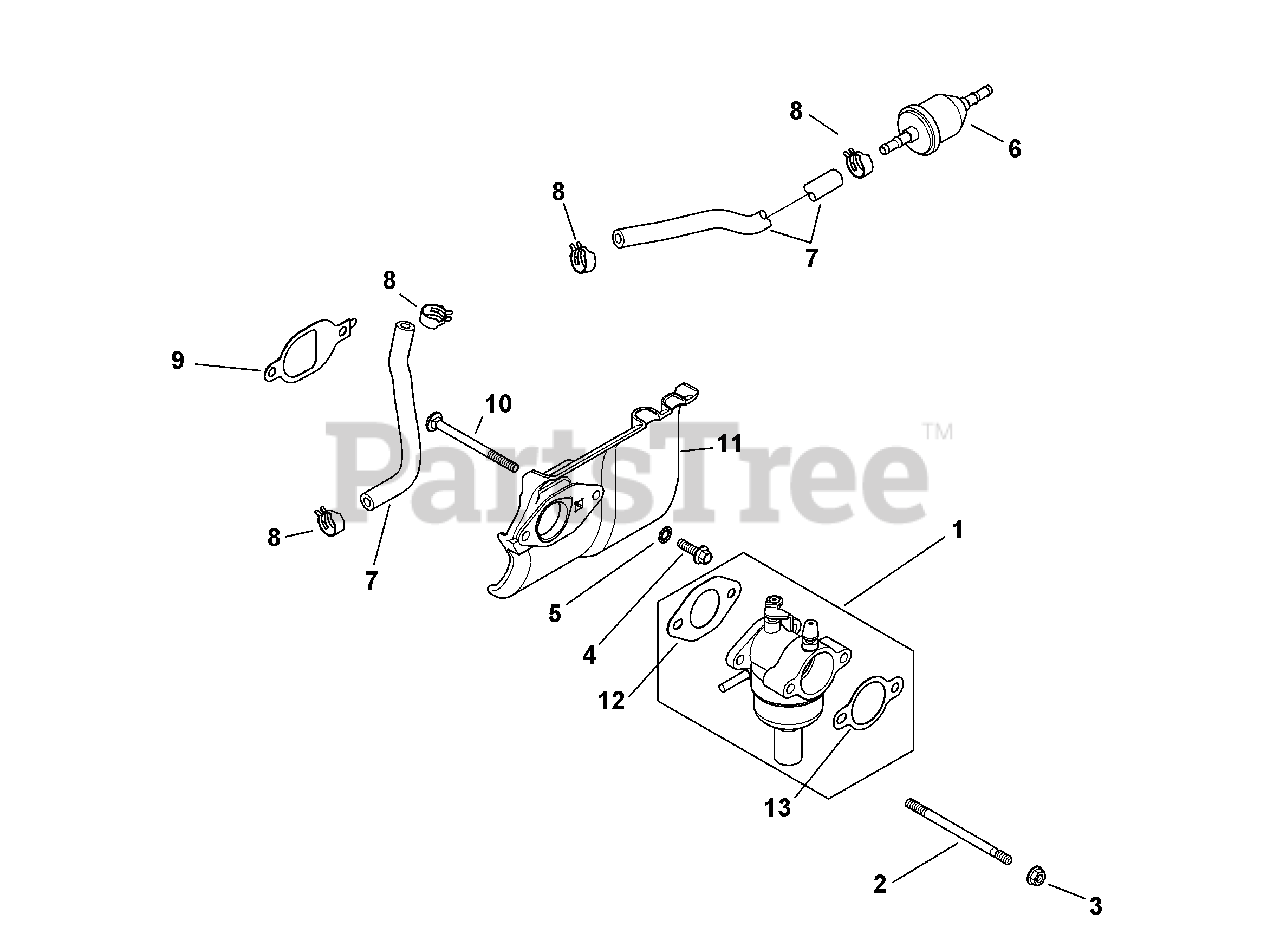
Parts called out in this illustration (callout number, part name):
1	Carburetor Kit (Inc. 12 & 13)
2	Stud, M6 X 1.0 X 100
3	Flange Nut, M6 X 1.0
4	Flange Screw, M6 X 1.0 X 20
5	Int. Tooth Lock Washer, 1/4
8	Hose Clamp, 1/2
9	Heat Deflector Gasket
10	Carburetor Stud
11	Heat Deflector Kit
12	Carburetor Gasket
13	Air Cleaner Base Gasket
